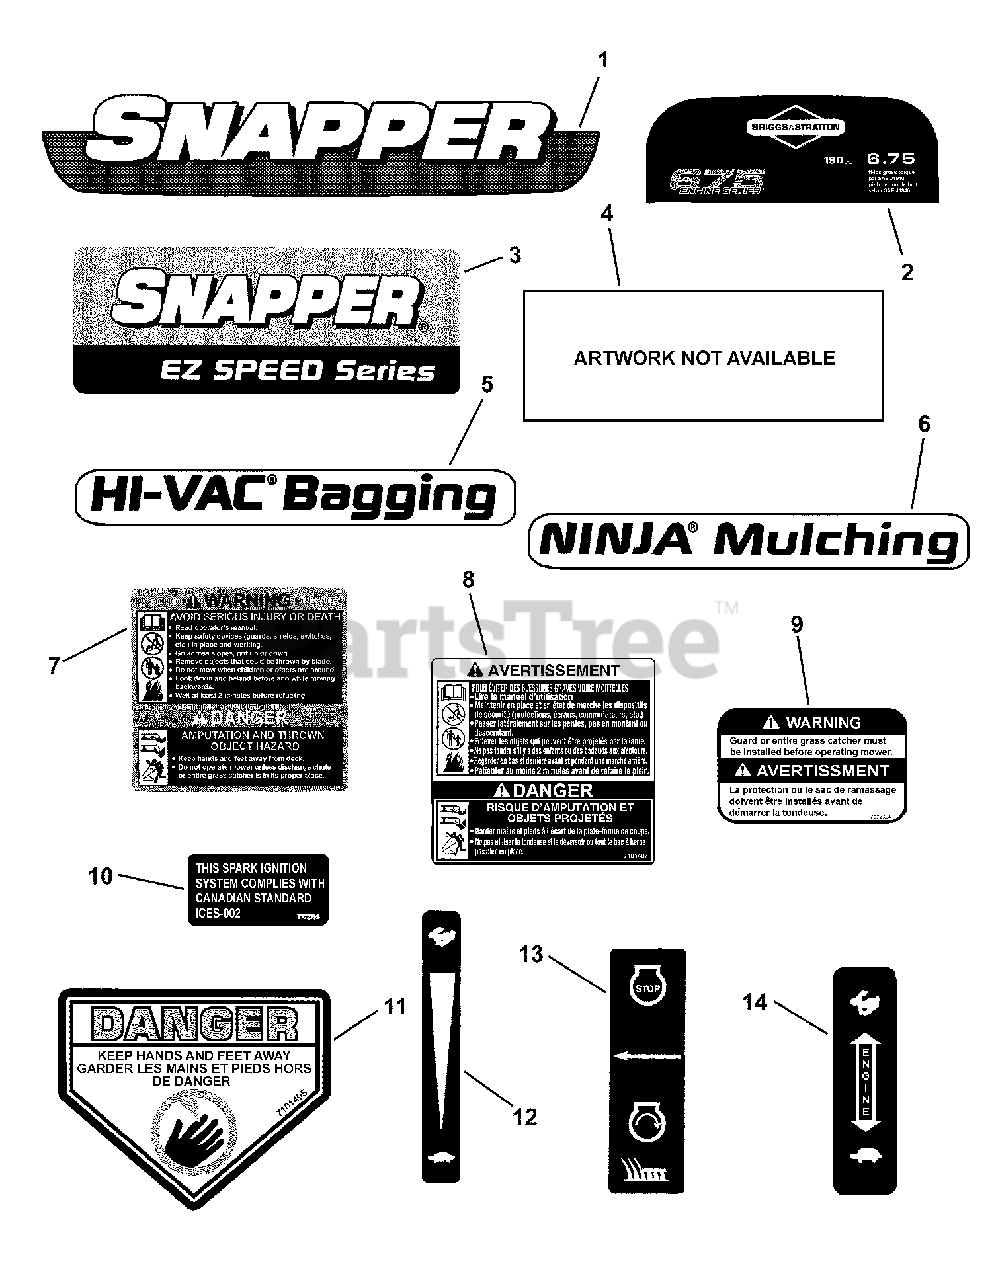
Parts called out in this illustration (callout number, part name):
1	DECAL, Briggs Engine, Snapper
2	DECAL, Engine, TP, 675, Snapper, FC
3	DECAL, Easy Speed, Control Panel
4	DECAL, Snapper Control Panel
5	DECAL, Front Cover, Hi-Vac
6	DECAL, Front Cover, Ninja Mulching System
7	DECAL, Warning/Danger Walk-Behind Mowers
8	DECAL, Warning/Danger- French/English
9	DECAL, Chute/Deflector FC
10	DECAL, Compliance, ICES
11	DECAL, CPSC French/English
12	DECAL, Speed Shift
13	DECAL, OPC Bail (International Symbol)
14	DECAL, Throttle Control, B&S
